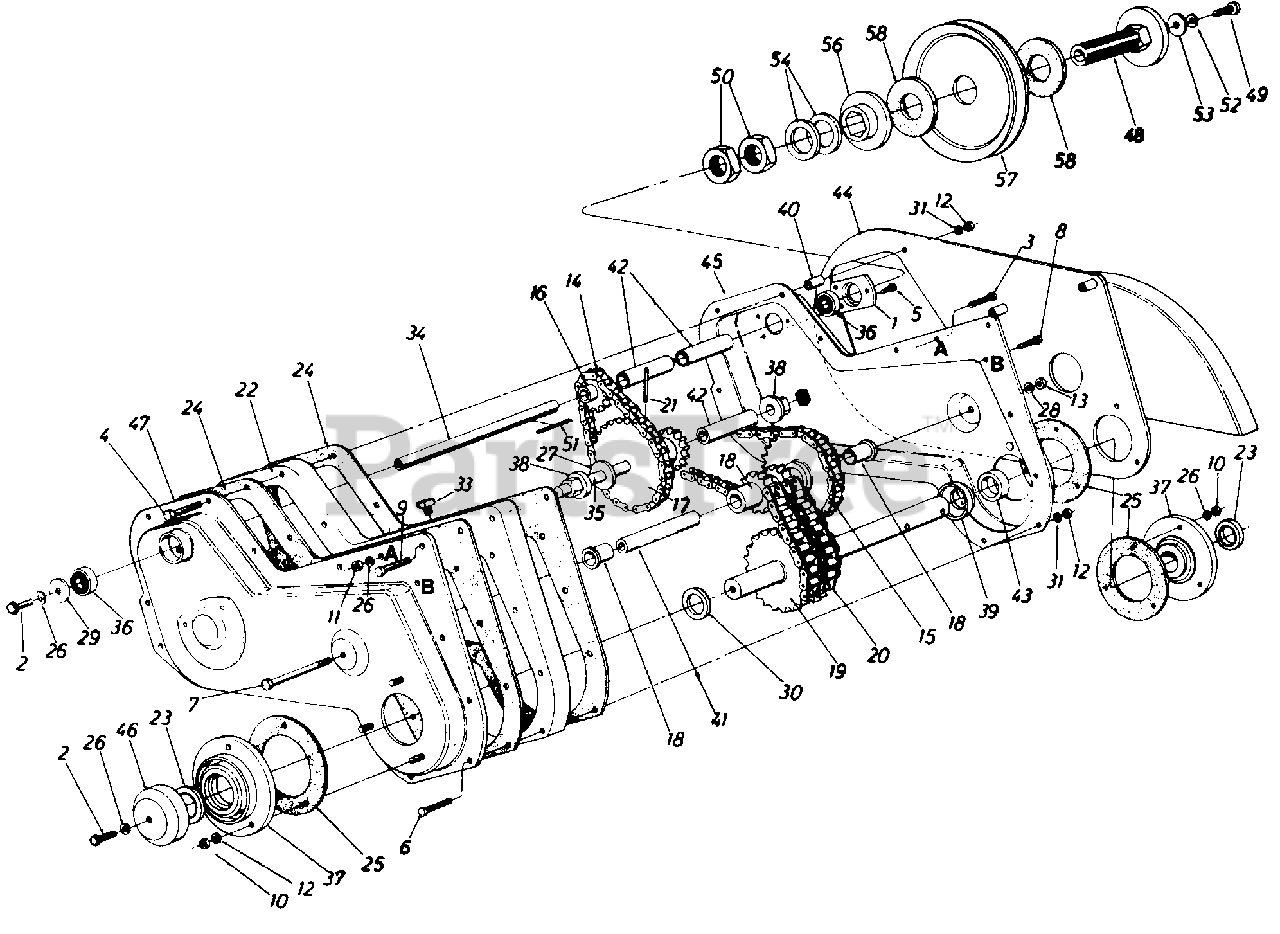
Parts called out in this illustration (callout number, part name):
1	Bearing Housing 1-3/8" Dia.
2	Hex Bolt 5/16-18 x .88"
3	Hex Bolt 5/16-18 x 1.5" Lg.
4	Hex Bolt 1/4-20 x 2.75" Lg.
5	Hex S-Tap Scr. 1/4-20 x .5" Lg.
6	Hex Bolt 1/4-20 x 1.5" Lg.
7	Hex Bolt 3/8-16 x 4.5" Lg.
8	Hex Scr. 1/4-20 x 1.5" Lg.
9	Hex TT-Tap Scr. 5/16-18 x 1.75"
10	Hex L-Nut 5/16-18 Thd.
11	Hex Nut 5/16-18 Thd.
12	Hex Nut 1/4-20 Thd.
13	Hex Nut 3/8-16 Thd.
14	#41 Chain 1/2" Pitch x 34 Links-Endless
15	#42 Chain 1/2" Pitch x 48 Links-Endless
16	Sprocket 10 Tooth .5" Pitch
17	10 & 28 Teeth Sprocket Ass'y.
18	8-2 & 28 Sprocket Sleeve Ass'y.
19	18-2 Sprocket Shaft Ass'y.
20	#50-2 Chain 5/8" Pitch x 28 Links-Endless
21	Spring,, LPin Spir. 1/4 Dia. x 1.5" Lg.
22	Spacer Block-Tiller Housing
23	Oil Seal 1-1/4" Dia.
24	Gasket for Tiller Housing
25	GasketforBrg. Housing
26	L-Wash. 5/16" I.D.
27	Fl-Wash. .64" I.D. x 1.24" O.D.
28	L-Wash. 3/8" I.D.-H.D.
29	Fl-Wash. .344" I.D. x 1.125"
30	Special Washer
31	L-Wash. 1/4" I.D.
33	Vent Plug
34	Jack Shaft .525" I.D. x 7.78"
35	Sprocket Shaft .63" Dia. x 5"
36	Ball Brg. .62" I.D. x 1.38" O.D.
37	Bearing Housing-1-1/4"
38	Hex Flange Brg.
39	Spacer 1.25" I.D. x 2.0" O.D.
40	Spacer .9" Lg.
41	Spacer 3.44" Lg.
42	Spacer 1.56" Lg.
43	Spacer .5" Lg.
46	Dust Cap
49	Hex Bolt 5/16-18 x 1.25" Lg. Grade 5
50	Hex Jam Nut 1.0-14 x 28 Thd.
51	Sq. Key 3/16 x 1.5" Lg.
52	L-Wash. 5/16" I.D.
53	Fl-Wash. .344" I.D. x 1.125"
54	Bell-Wash. 1.0" I.D. x 2.0"
56	Floating Disc 3-1/4" O.D.
57	5/8 V-Pulley 1.5" I.D. x 6.5"
58	Friction Pad 3-1/4" O.D. x 1-3/8" I.D.
